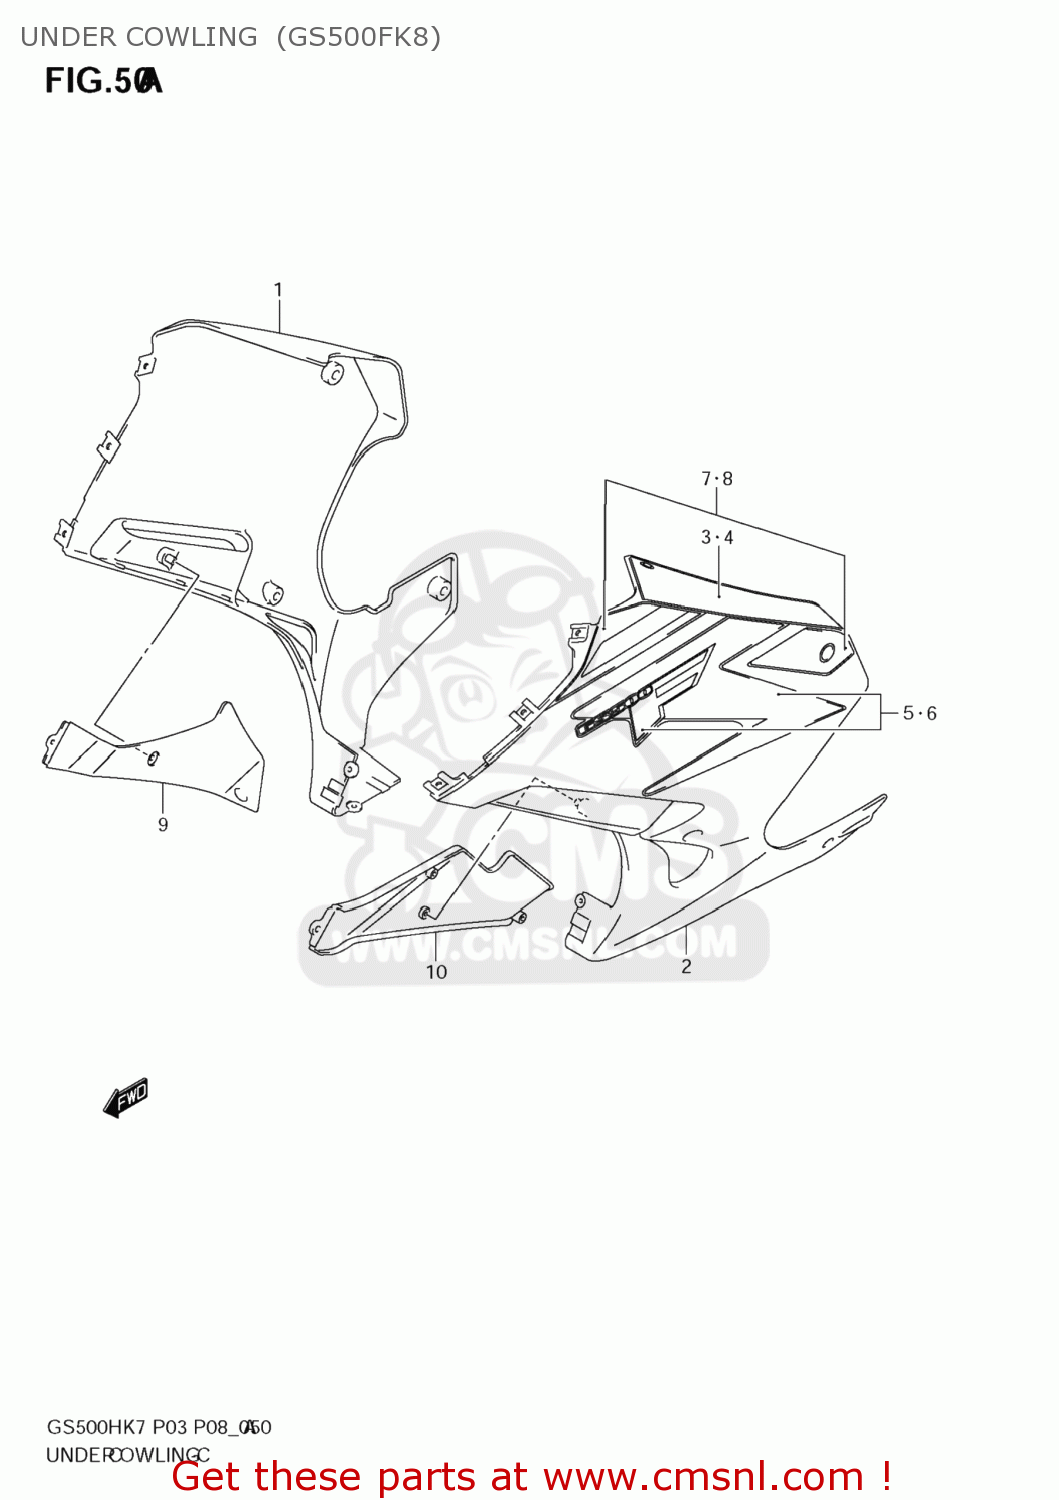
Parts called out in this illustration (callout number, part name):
1	COWL, UNDER RH (WHITE)
2	COWL, UNDER LH (WHITE)
3	TAPE GS500
4	TAPE,UPPER
5	TAPE,UPPER RH
6	TAPE,UPPER LH
7	TAPE SET,RH SID
8	TAPE SET,LH SID
9	COWLING, INNER
10	COWLING, INNER
11	SHIELD,UNDER C
12	SHIELD,UNDER C
13	SHIELD,UN. HEA
14	SHIELD,UN.HEAT
